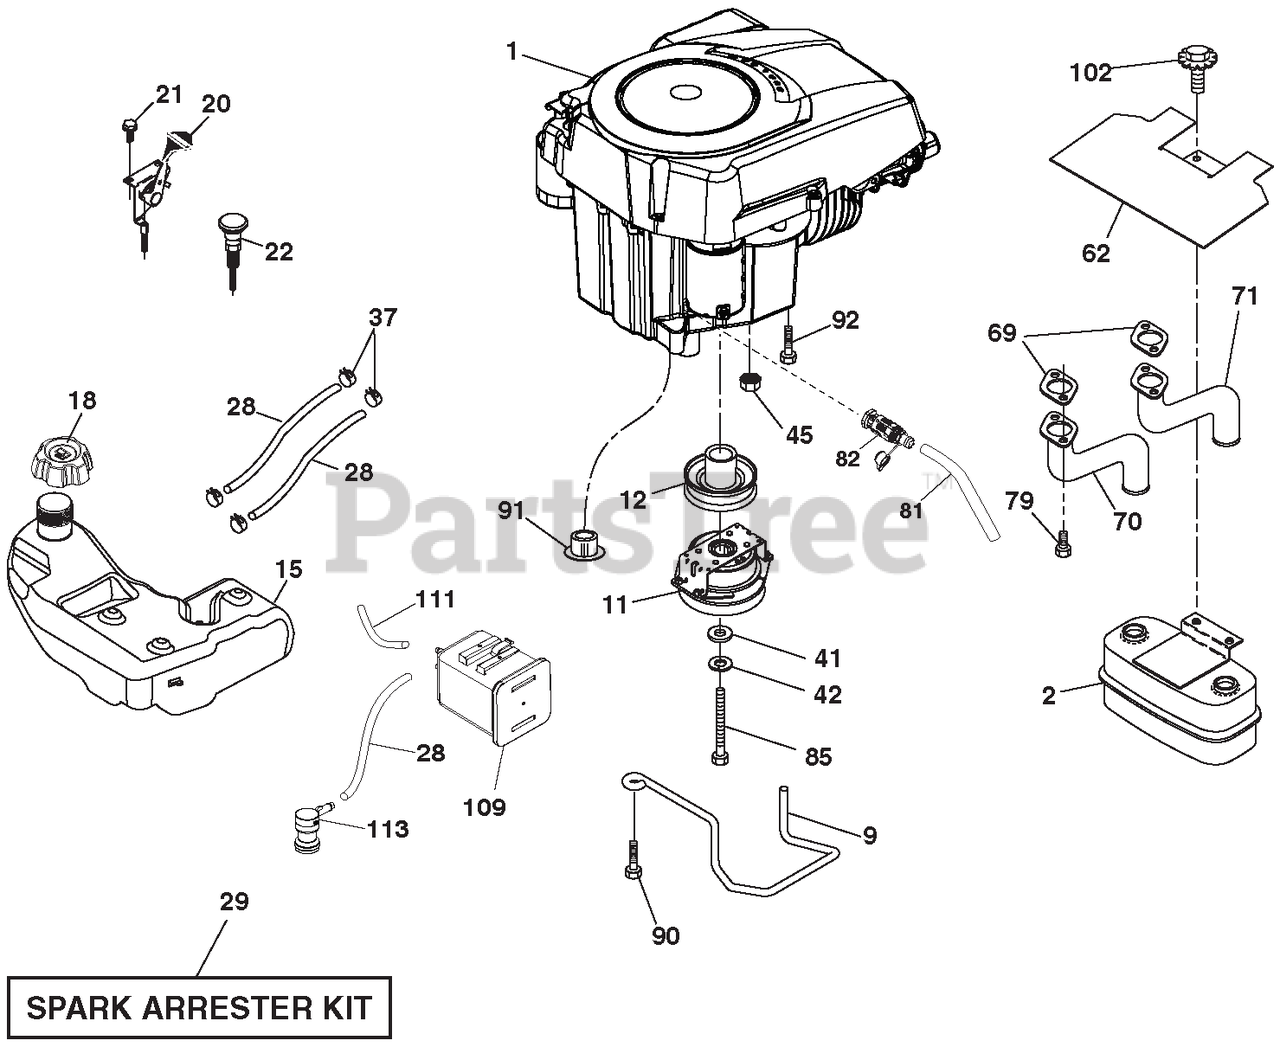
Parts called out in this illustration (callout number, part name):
2	MUFFLER ASM.TWIN.LO-TONE
9	KEEPER.BELT.ENGINE
11	ELECT. CLUTCH
12	ENGINE PULLEY
15	TANK.FUEL.ASM.3.00 GA.
18	CAP FUEL
20	CONTROL.THROTTLE
22	CONTROL CHOKE
28	LINE.FUEL.64"REAR.EMIS.CA.LP
29	KIT.SPARK ARRESTOR(392390 B&S)
37	CLAMP.HOSE.BLK.
41	WASHER.1-1/2 ODX15/32 IDX.250
42	WASHER.LOCK.HVY HLCL.SPR.7/16
45	Nut, Keps Hex 1/4-20 unc
62	SHIELD.HEAT.MUFFLER.
70	EXHAUST TUBE LH
71	EXHAUST TUBE RH
79	SCREW.SOCKET HD.5/16-18 X .75
81	TUBE.DRAIN.OIL.EASY
82	VALVE OIL DRAIN
90	SCREW.3/8-16X1.SMGML.TAP/R.BLK
91	BUSHING.1.375OD.HEYCO 2210
92	SCREW.3/8-16 X 1.SMGML.TAP/R
102	SCREW.5/16-18X3/4.SMGML.TAP/BL
109	CANISTER.CARBON.FILTER ASM.TEX
111	PURGE.LINE.CARB
113	VALVE.SLANT.CARTIDGE
